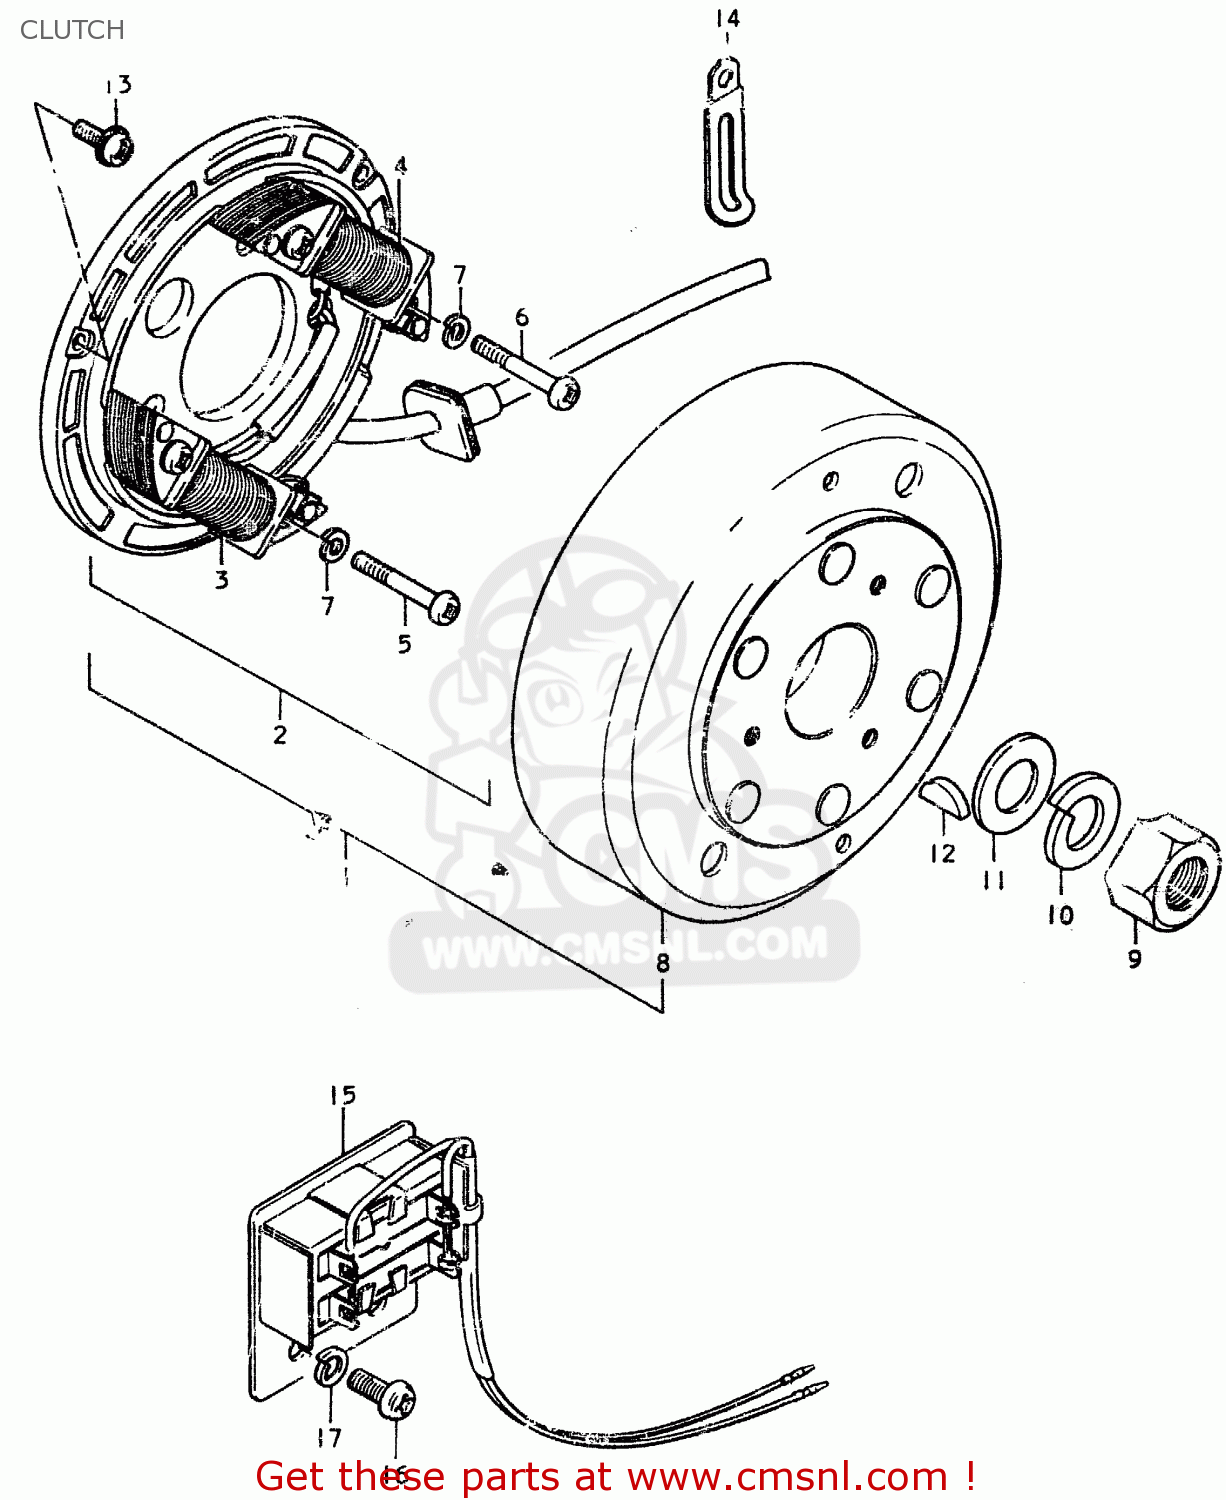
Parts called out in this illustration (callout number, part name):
1	GEAR ASSEMBLY,PRIMARY DRIVE
2	WASHER(25X54X2.5)
3	BEARING(35X40X39.8)
4	HUB,CLUTCH SLEEVE
5	NUT
6	WASHER,LOCK
7	WASHER
8	PLATE,CLUTCH DRIVE (MCA)
9	PLATE,CLUTCH DRIVEN(T:2.0) (NAS)
10	PLATE,CLUTCH PRESSURE
11	SPRING
12	BOLT, UPPER
13	WASHER
14	SEAT,WAVE WASHER
15	RING,STOPPER
16	WASHER
17	GEAR,OIL PUMP DRIVE
18	PIN(6X6)
19	PIECE,CLUTCH PUSH
20	BEARING(15X28X2)
21	WASHER
22	ROD,CLUTCH PUSH
23	ROD,CLUTCH PUSH,L
24	OIL SEAL
25	SCREW ASSY,CLUTCH RELEASE
26	SCREW(6X25)
27	NUT 6MM
28	SCREW
29	SPRING
